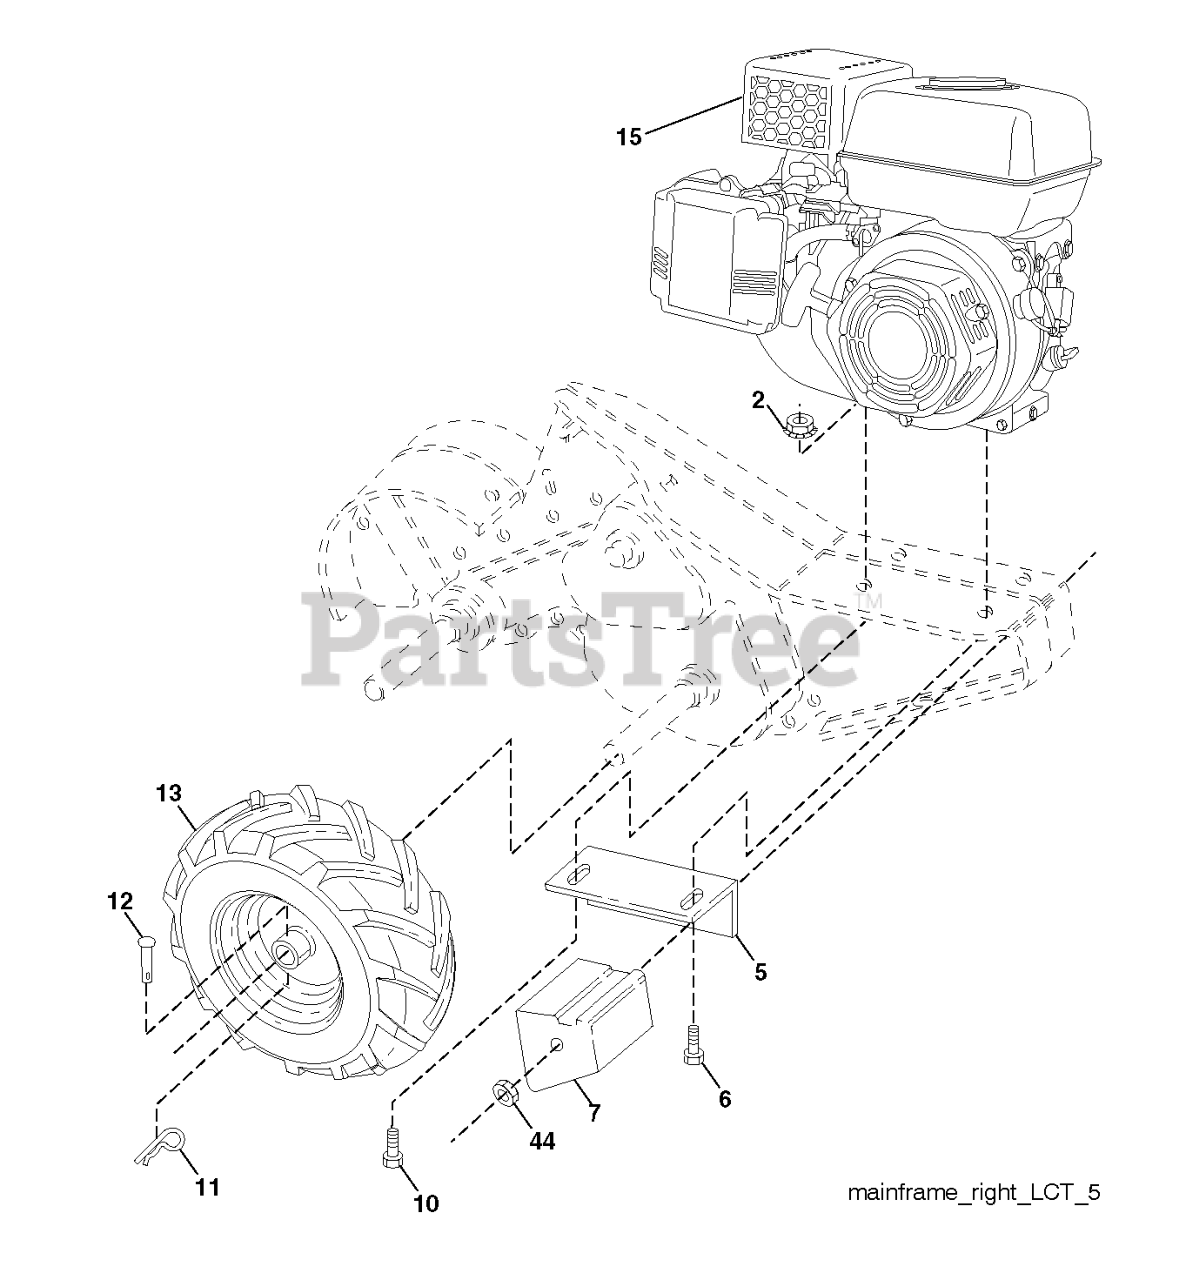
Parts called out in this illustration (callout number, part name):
2	LOCKNUT-FLANGE 5/16-18
5	BRACKET.REINFORCEMENT.RH.BLACK
6	BOLT, HEX 5/16-18X1-3/4
7	COUNTERWEIGHT.RH
10	BOLT
11	RETAINER M
12	RIVET
13	WHEEL ASM.16 X 4 X 8.DR.RH.421
15	ENGINE LCT, 208CC, TILLER
